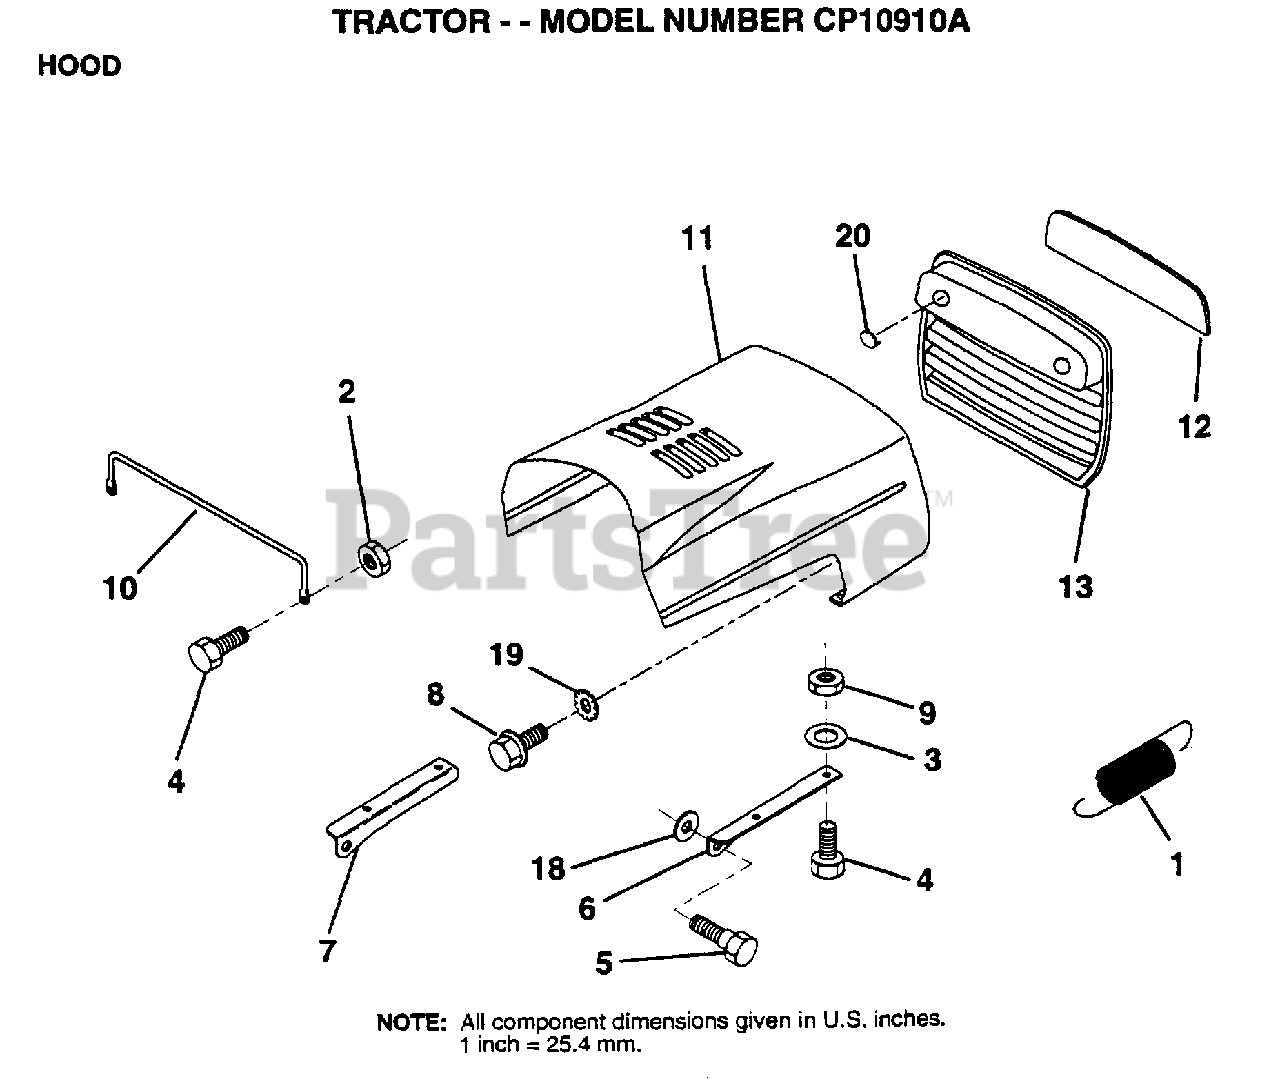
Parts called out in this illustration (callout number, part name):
1	EXT SPRING
2	NUT HXKEP 1/4X20
3	WASHER
5	BOLT.SHLD.5/16-18
6	BRKT HOOD RH
7	BRKT HOOD LH
8	SCREW SLTD HXHD
9	NUT
10	"BRACE,HOOD"
11	HOOD
12	LENS
13	GRILL
18	WASHER
19	LOCKWASHER GT
